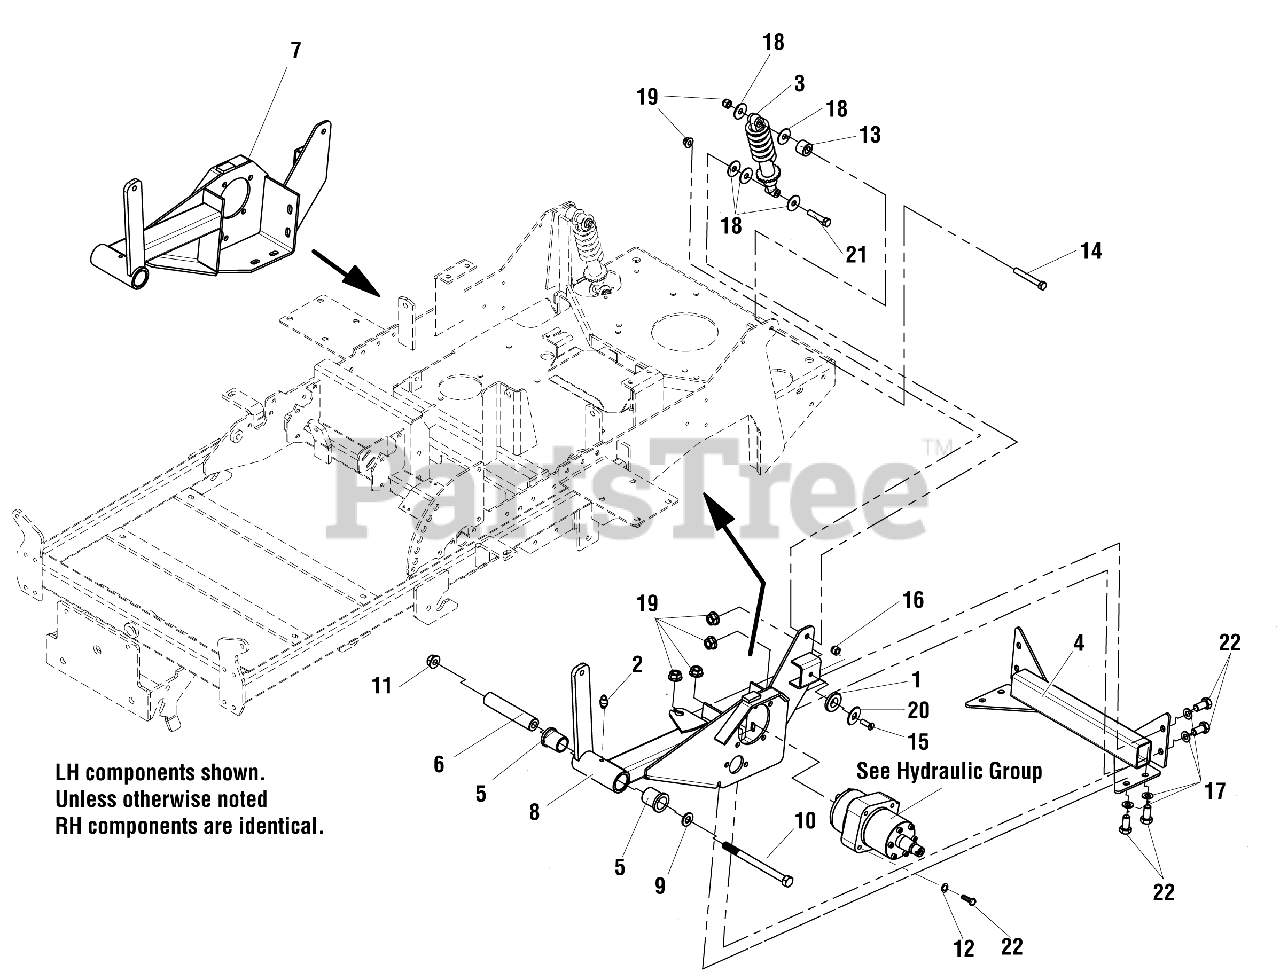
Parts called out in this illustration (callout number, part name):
1	SPACER, .34 X 1.54 X .25 UHMW
2	GREASE FITTING, 1/4-28 STRAIGHT
4	WELD, TIE BAR, ORANGE
5	BUSHING, FLANGE
6	SPACER, .52 X 1.00 X 5.00
7	WELD, TRAILING ARM, RH, ORANGE
8	WELD, TRAILING ARM, LH, ORANGE
9	WASHER, 1/2" SAE
10	BOLT, 1/2-13 X 6-1/2 GD8, YZ
11	NUT, 1/2-13 HEX NYLOCK FLANGE
12	WASHER, 3/8" SPLIT LOCK
13	SPACER, .39 X 1.00X .63
14	BOLT, 3/8-16 X 2-1/2" GD5 YZ
15	SCREW, 5/16-18 X 1, PHILLIPS HD, BZ
16	NUT, 5/16-18 HEX NYLOCK FLANGE
17	WASHER, 3/8" GD.9 FLAT
18	WASHER, 3/8" FENDER
19	NUT, 3/8-16 HEX NYLOCK FLANGE
20	WASHER, .41 X 1.75 X .14
21	BOLT, 3/8-16 X 1-3/4" GD5
22	BOLT, 3/8-16 X 1" GD5 YZ
